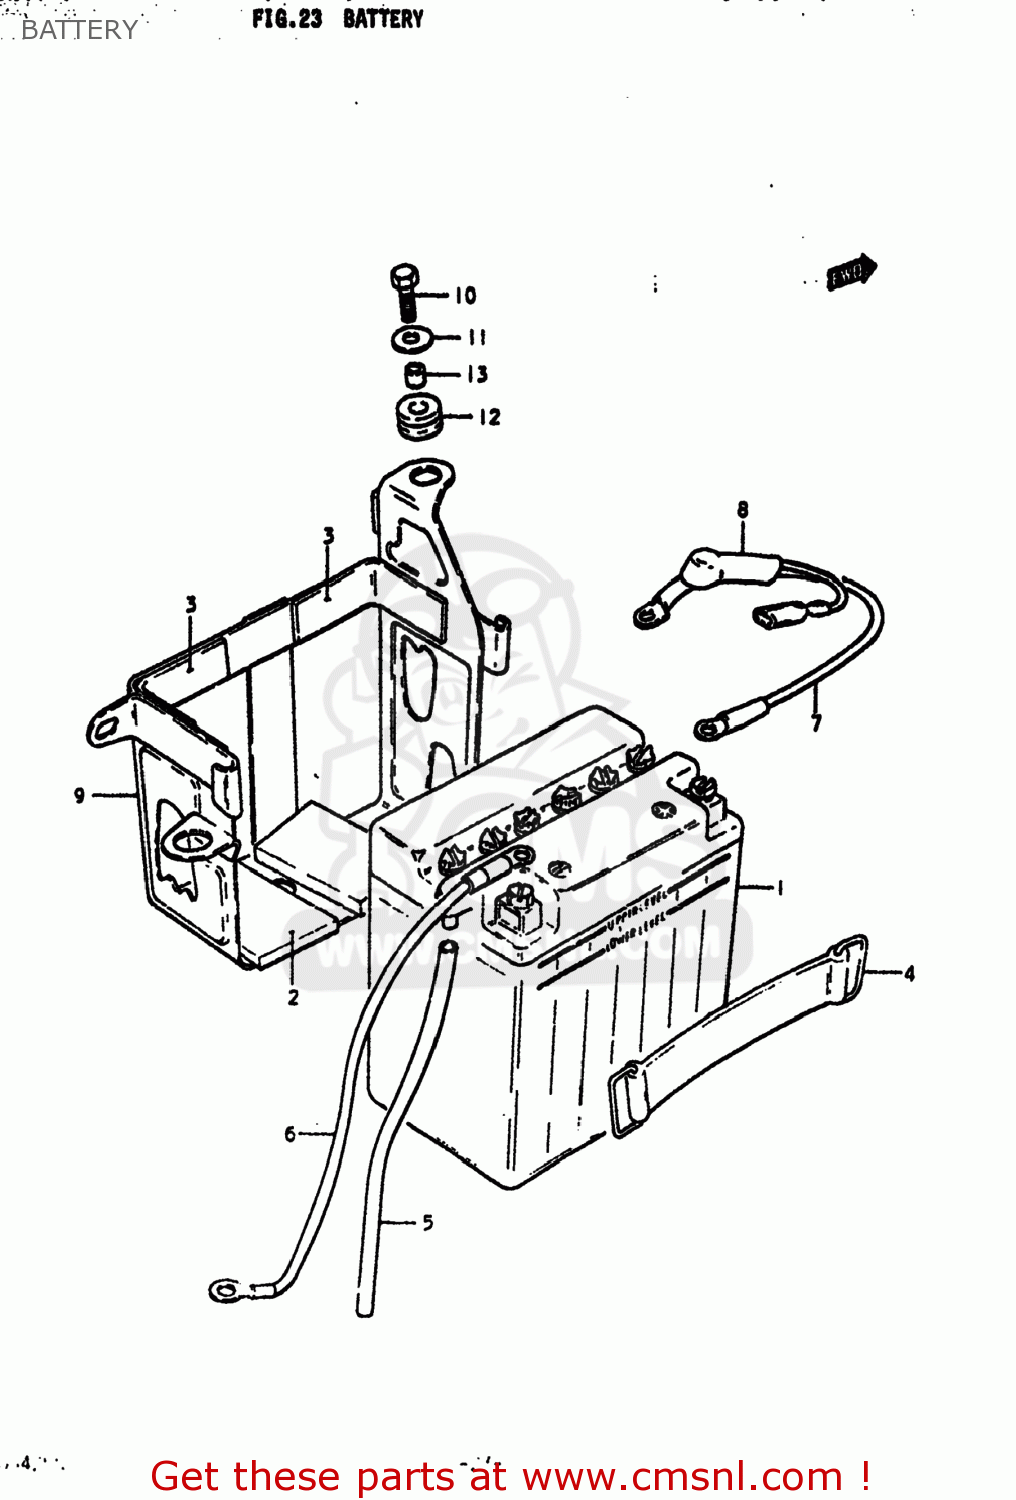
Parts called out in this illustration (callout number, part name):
1	BATTERY ASSY (12V)
2	CUSHION,BATTERY
3	PROTECTOR,20X9
4	BAND
5	HOSE,BATTERY EXHAUST
6	CORD,BATTERY MINUS
7	WIRE,BATTERY PLUS
8	CAP,TERMINAL
9	HOLDER,BATTERY
10	BOLT
11	WASHER
12	CUSHION
13	SPACER (6.1X9X9)
